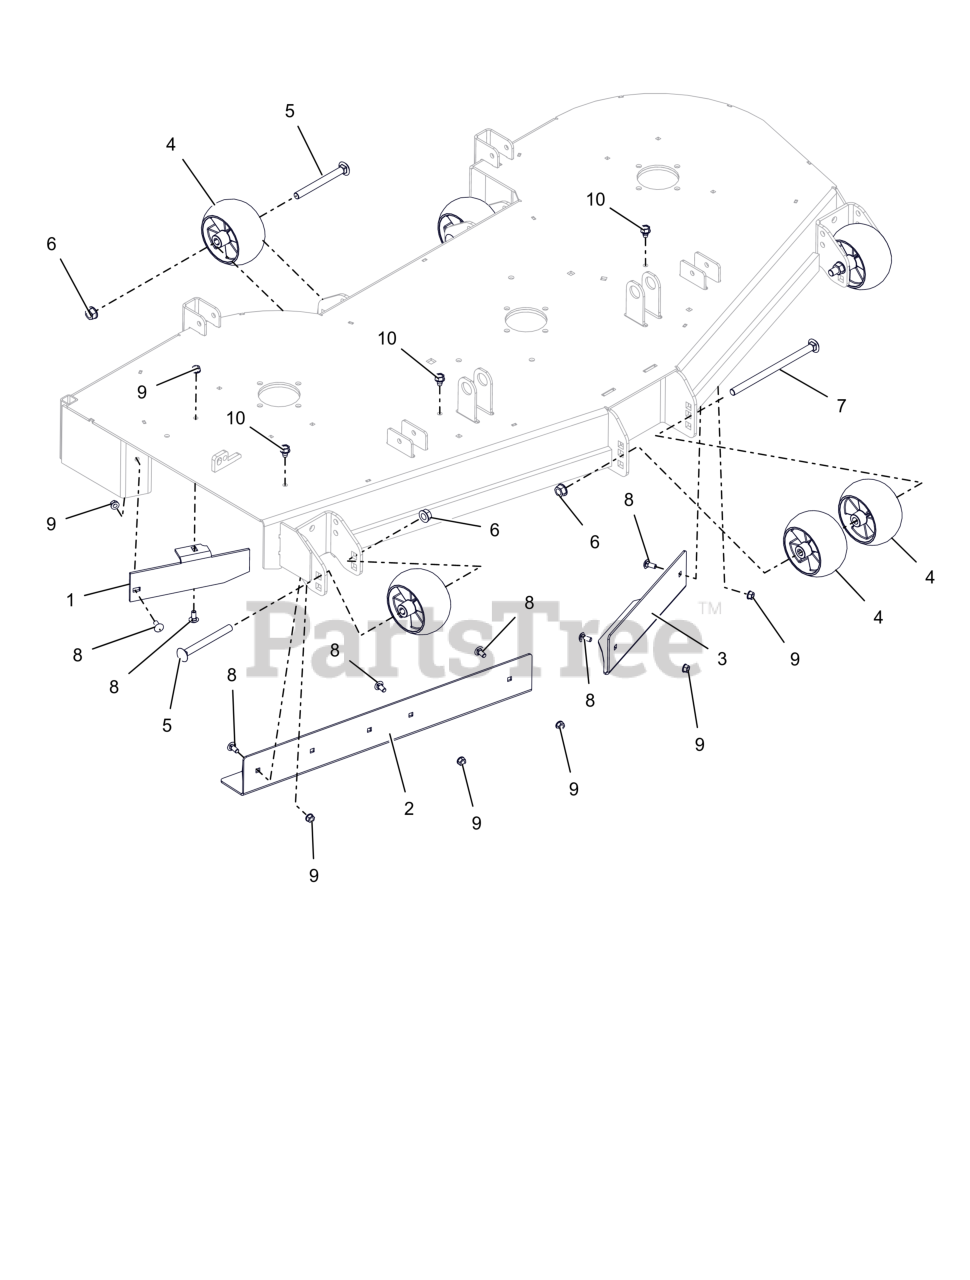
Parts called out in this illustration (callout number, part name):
1	60" DISCHARGE BAFFLE - RED
2	BAFFLE, 60" RH VACUUM (RED)
3	BAFFLE, 60" LH VACUUM (RED)
4	WHEEL, ANTI SCALP - 5X3 CTR W/RIBS
5	BLT, RHSN .50-13X5.00 G5 ZCC
6	NUT-LK-CTR-FLG .500-13 GG ZCC
7	BTL,RHSN .500-13 X 8.5S G5 ZCC
8	BLT,RHSN .31-18X.75 G5 ZCC
9	NUT,LK-CTR-FLG .31-18 GF ZCC
10	SCR,TAP .375-16X.50 HWH TR ZCC
